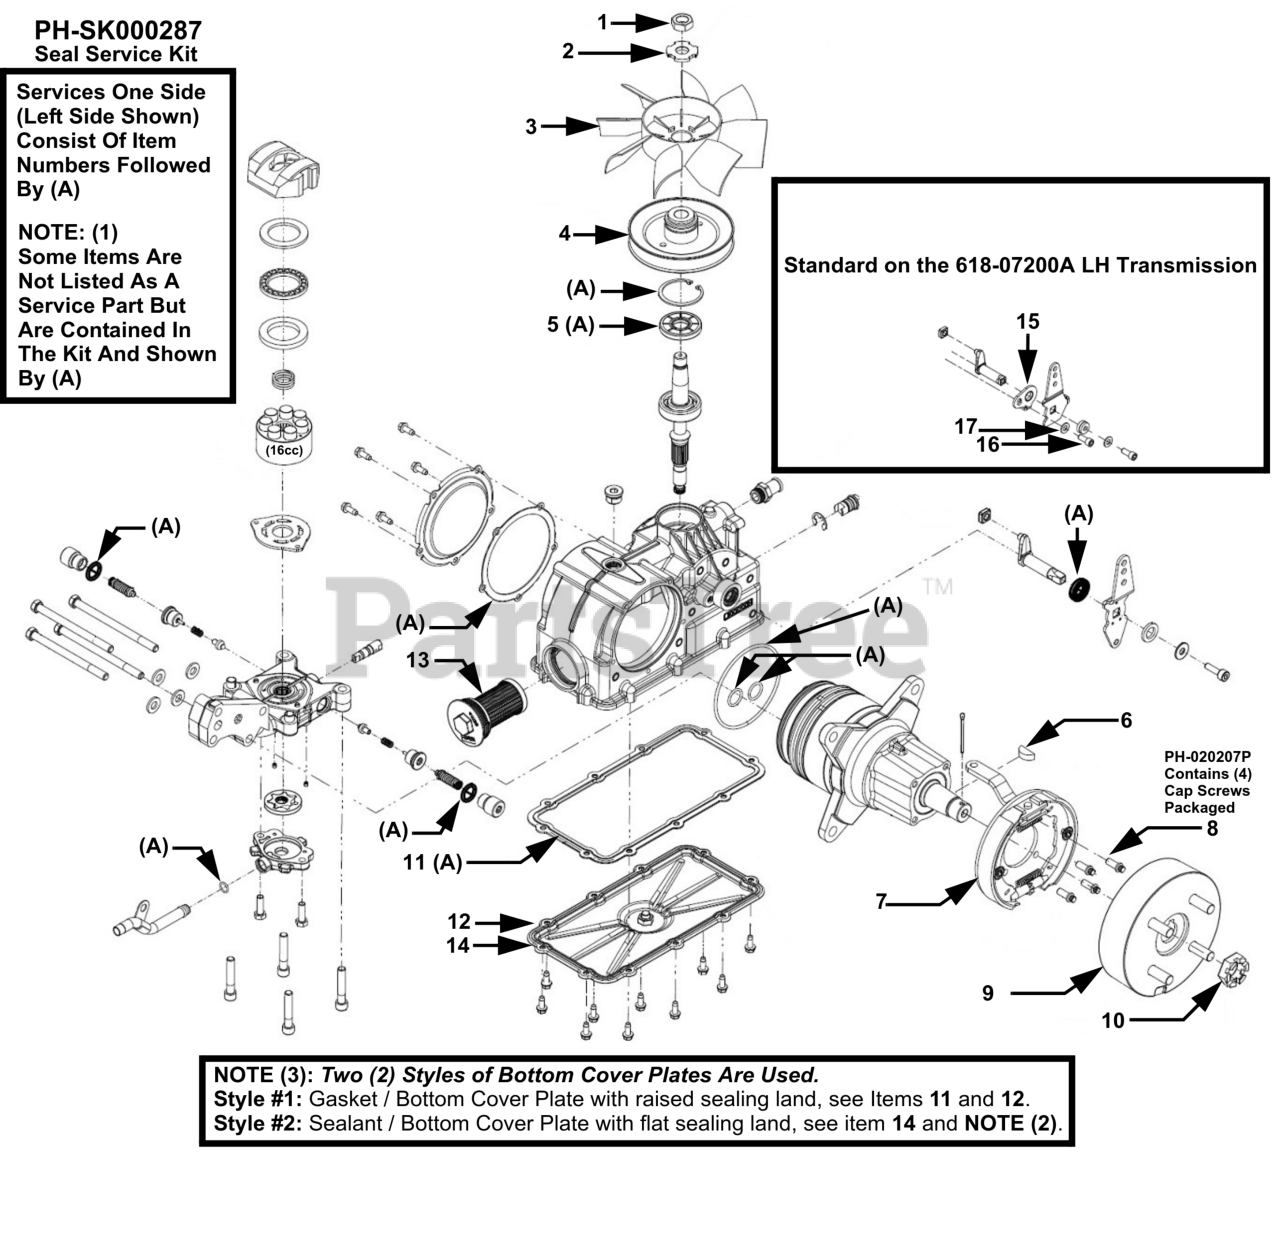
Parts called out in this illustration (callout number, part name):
6	WOODRUFF KEY
7	BRAKE ASSEMBLY-ON HOLE LEVER
8	SCREW-CAP (QTY 4)
9	DRUM-4 BOLT BRAKE
10	NUT-SLOTTED
11	BOTTOM COVER GASKET
12	BOTTOM COVER
14	BOTTOM COVER
15	TRUNNION ARM BRACKET (LH)
16	CAP SCREW 5/16-24
17	FLAT WASHER
A	SEAL SERVICE KIT
